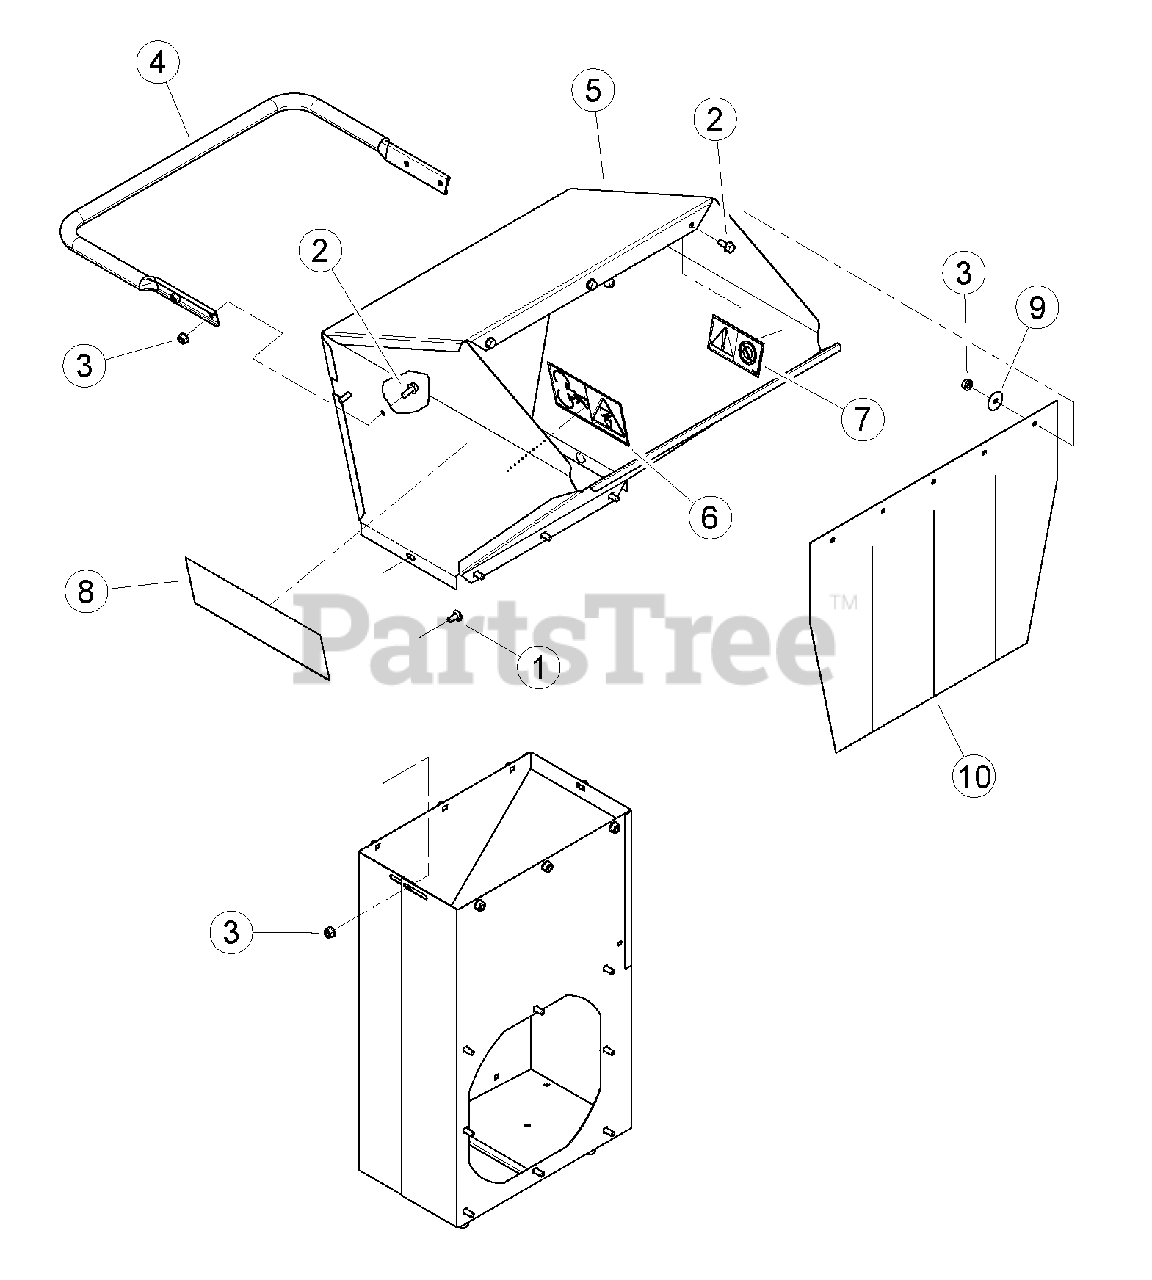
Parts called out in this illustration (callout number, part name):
1	BOLT, 5/16-18 X 3/4 CRG GR5 SN
2	BOLT, 5/16 X 3/4 FLANGE NC
3	NUT, 5/16-18 NYLOCK-FLANGE
4	HANDLE, EURO HOPPER
5	ASSEMBLY, EUROPEAN WIDE HOPPER
6	DECAL, BLADE DANGER ISO
7	DECAL, SHREDDER SIZE ISO
8	DECAL, ECHO BEARCAT 12.00 X 4.00
9	WASHER, 5/16" FENDER ZP
10	BELTING, EURO HOPPER
